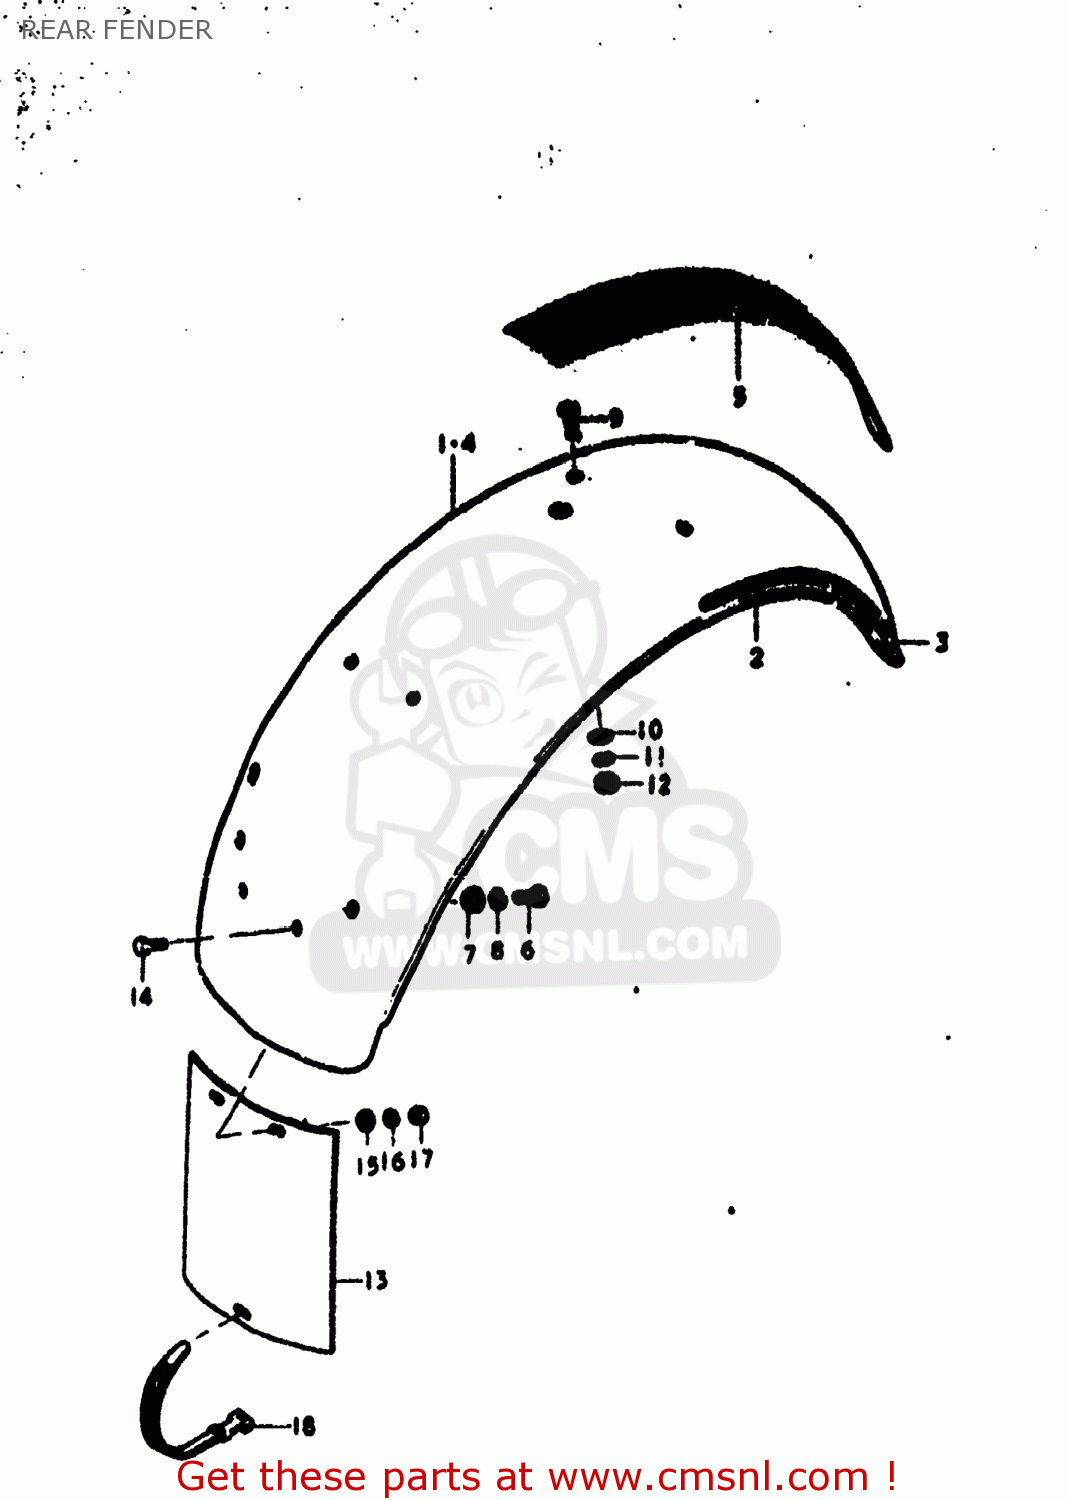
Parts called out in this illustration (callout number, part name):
1	FENDER,REAR
2	TAPE,FRONT FENDER
4	FENDER,REAR
6	BOLT
7	WASHER
8	LOCK WASHER
9	BOLT
10	WASHER
11	LOCK WASHER
12	NUT
13	MUD GUARD,REAR FENDER
14	BOLT
15	WASHER
16	LOCK WASHER
17	NUT
18	CLAMP(L:120)
